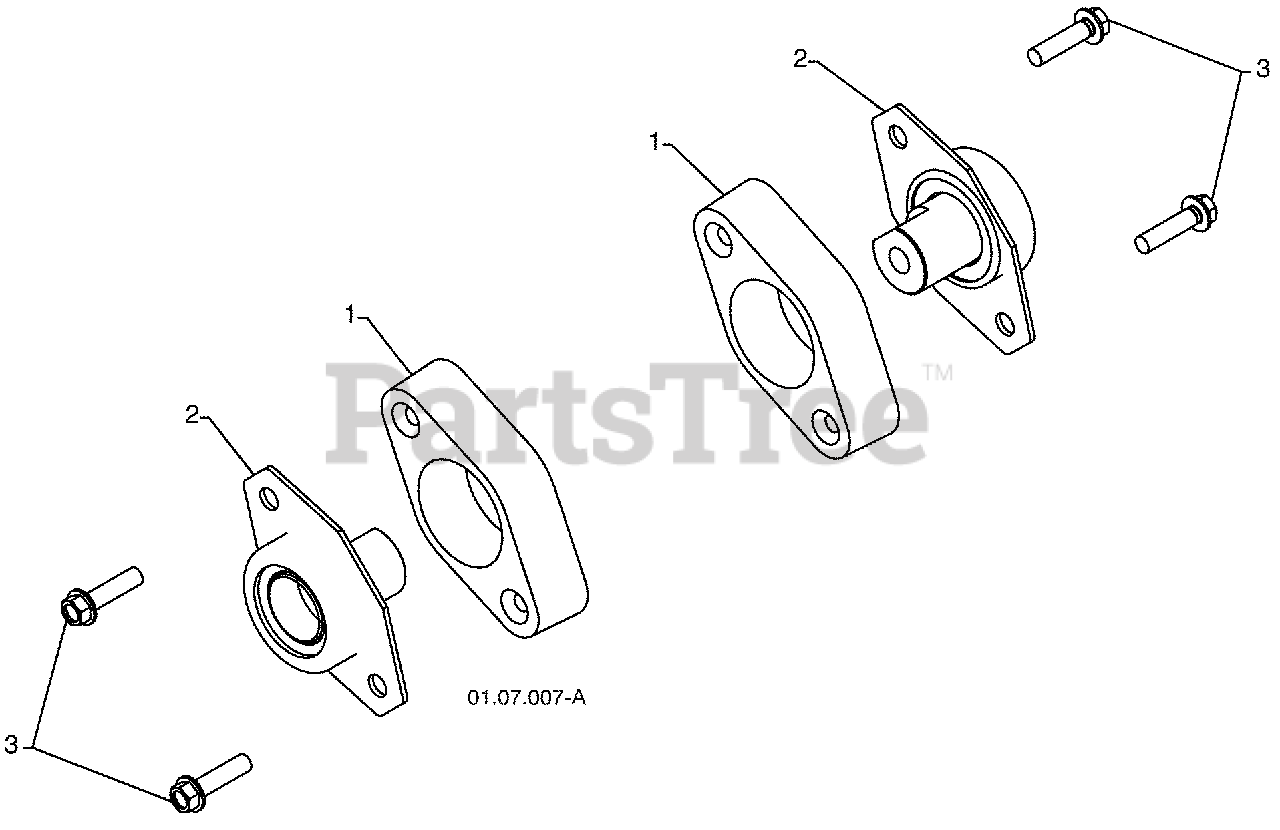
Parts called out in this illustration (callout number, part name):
1	PLASTIC RETAINER
2	AUGER BALL BEARING
3	SCREW 5/16-18 X 1.00
